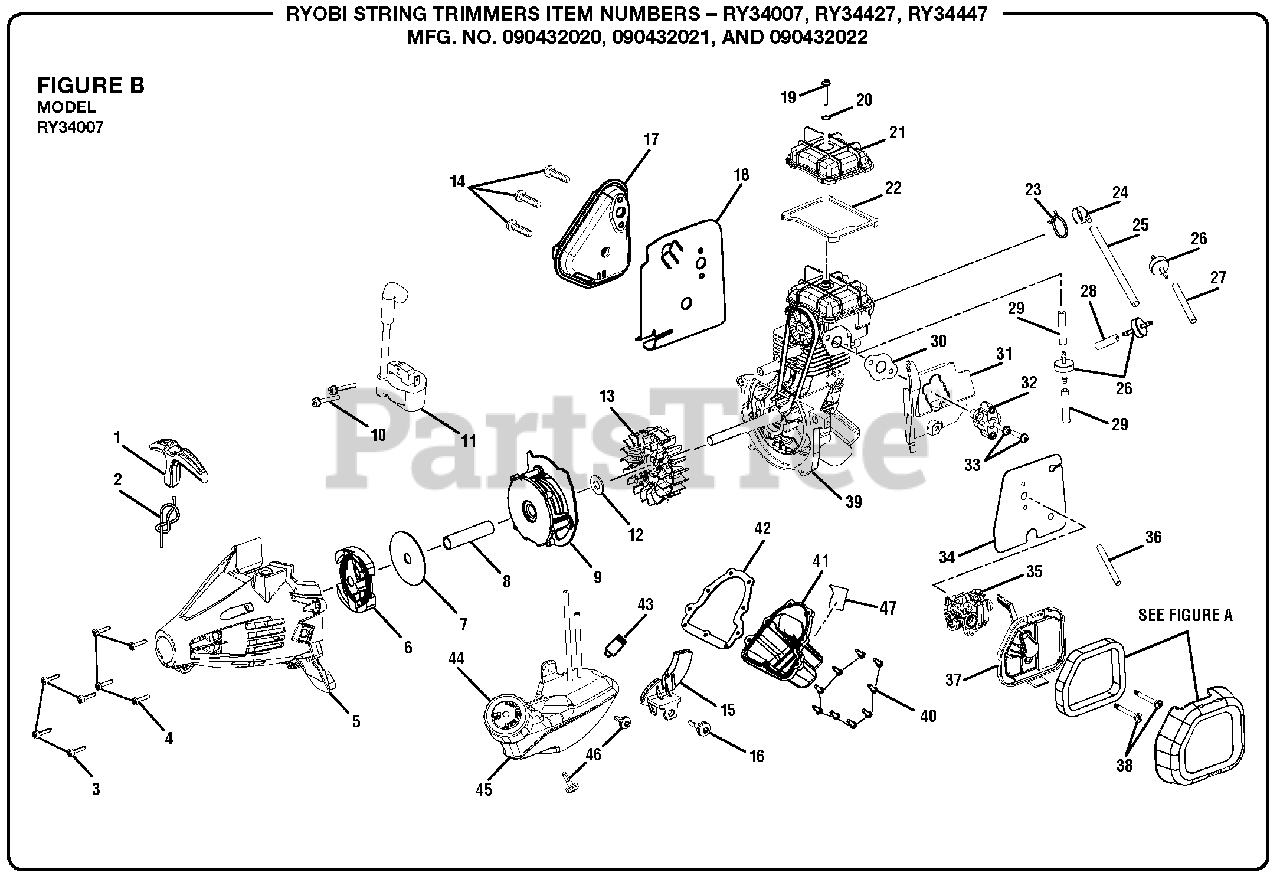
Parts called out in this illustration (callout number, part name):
1	Starter Grip
2	Starter Rope
3	Screw (M4 x 18 mm, T20 Torx Soc. Hd.)
4	Screw (M4 x 16 mm, T20 Torx Soc. Hd.)
5	Starter Housing Assembly
6	Clutch Assembly
7	Washer (ID9.63 x OD50.75 x 1.10t)
9	Starter Housing Assembly
10	Screw (M4 x 19 mm, T20 Torx Pan Hd.)
11	Ignition Module
12	Washer (ID9.75 x OD20 x 1.6t)
13	Flywheel Assembly
14	Screw (M5 x 42 mm, T25 Torx Truss Hd.)
15	Throttle Cable Guide
16	Shoulder Screw (M4 x 19 mm, T25 Torx Truss Hd.)
17	Muffler Assembly
18	Muffler Gasket
19	Screw (M4 x 27 mm, T20 Torx Truss Hd.)
21	Cam Cover
22	Cam Cover Gasket
23	Wire Clamp
24	Breather Fitting
25	Breather Hose (120 mm)
26	Check Valve
27	Shield Sleeve (M6 x 50 mm)
28	Breather Hose (24 mm)
29	Breather Hose (34 mm, Crankcase)
30	Heat Dam Gasket
31	Air Baffle
33	Screw (M5 x 23 mm, T25 Torx Pan Hd.)
34	Heat Shield w/Gasket (Carburetor)
35	Carburetor
36	Breather Hose (50 mm)
37	Air Box Base Assembly
38	Screw (M5 x 44 mm, T20 Torx Hd.)
39	Short Block Assembly
40	Screw (M4 x 12 mm, T20 Torx Hd.)
41	Oil Pan (Inc. Key No. 47)
42	Oil Pan Gasket
43	Fuel Filter
44	Fuel Cap Assembly
45	Fuel Tank w/Cap
46	Shoulder Screw (M4 x 14 mm, T25 Torx Truss Hd.)
47	Hot Surface Label
